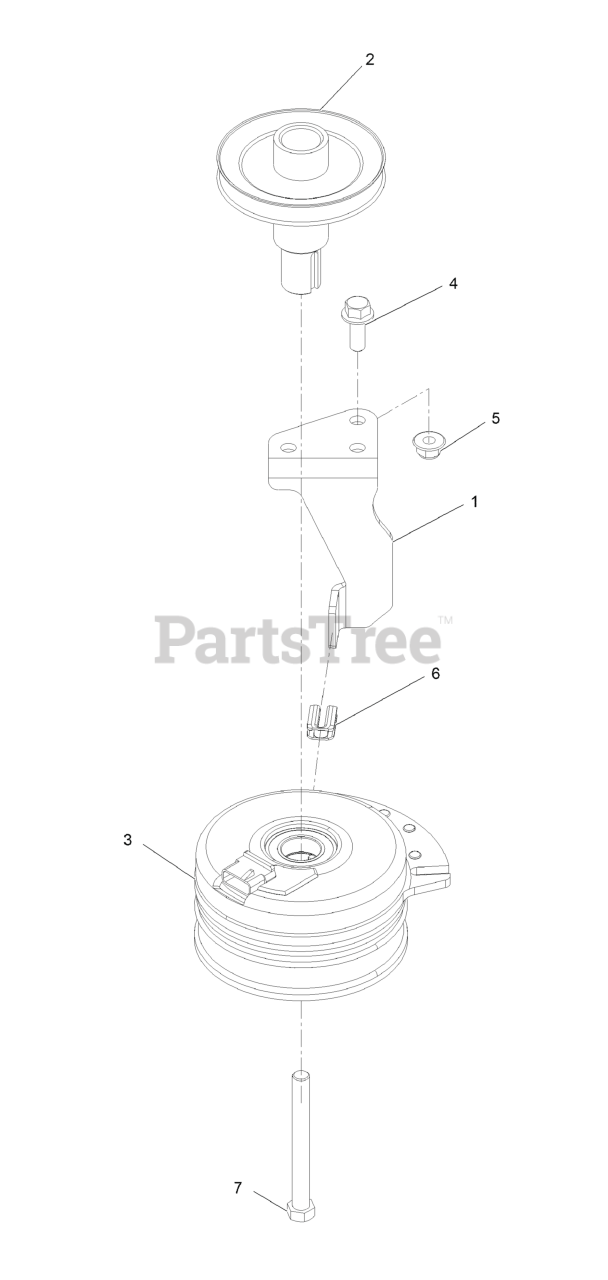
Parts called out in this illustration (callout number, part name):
1	Stop - Clutch (Narrow)
2	Pulley-Engine
3	CLUTCH-ELECTRIC
4	SCREW-HHF 3/8-16 X 1
5	NUT-HF, NI
6	ISOLATOR-CLUTCH
7	SCREW-HH
